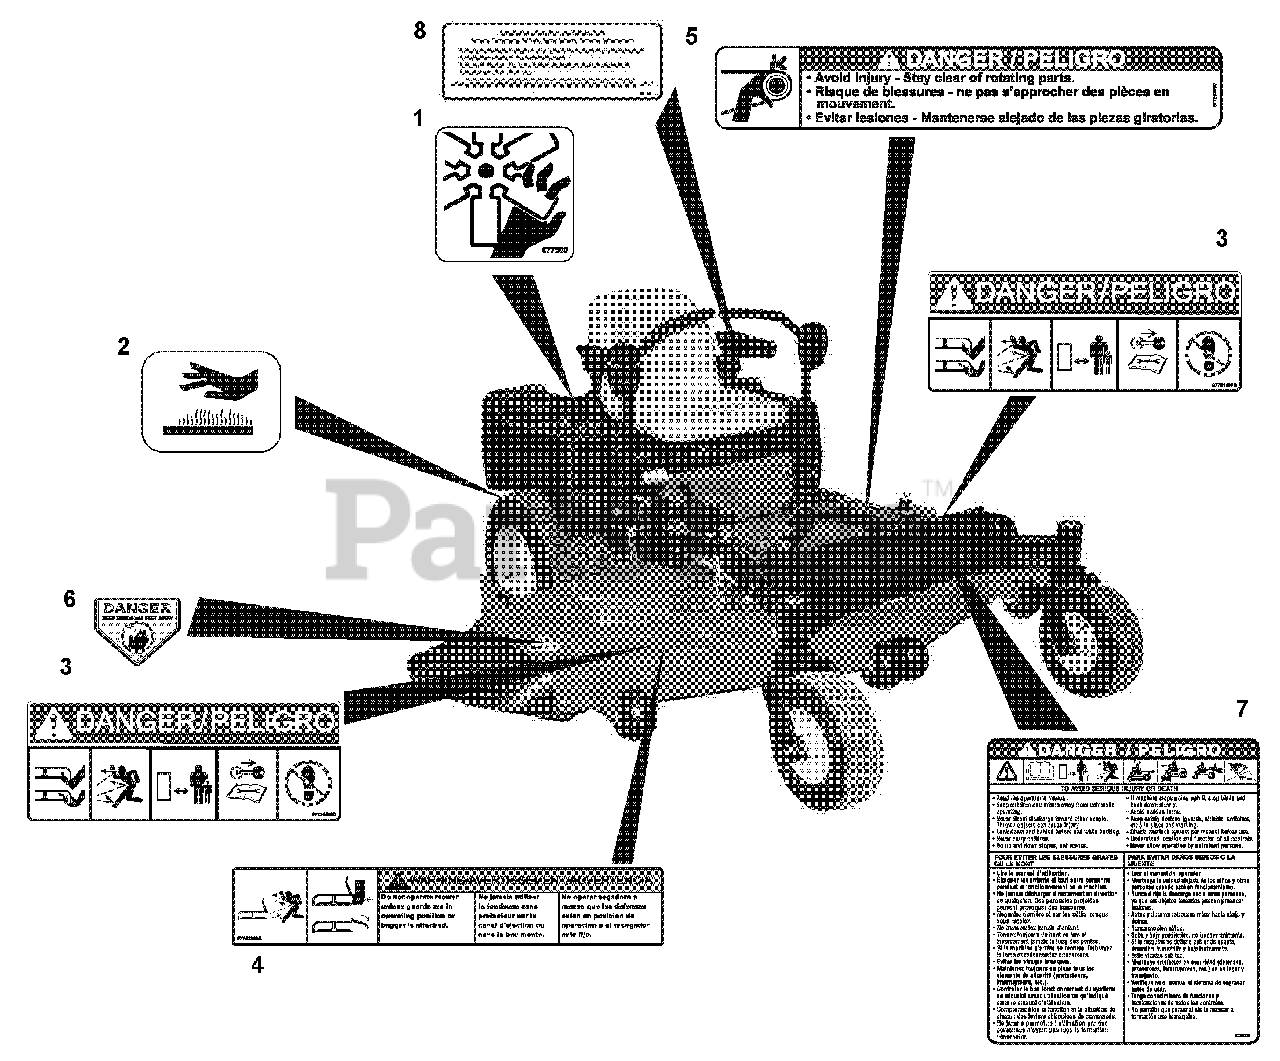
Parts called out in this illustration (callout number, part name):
1	Decal, Danger Fan
2	Decal, Hot Surface
3	Decal, Mower Pan Danger
4	Decal, Warning
5	Decal, Danger
6	Decal, Danger
7	Decal, Danger
8	Decal, EPA
